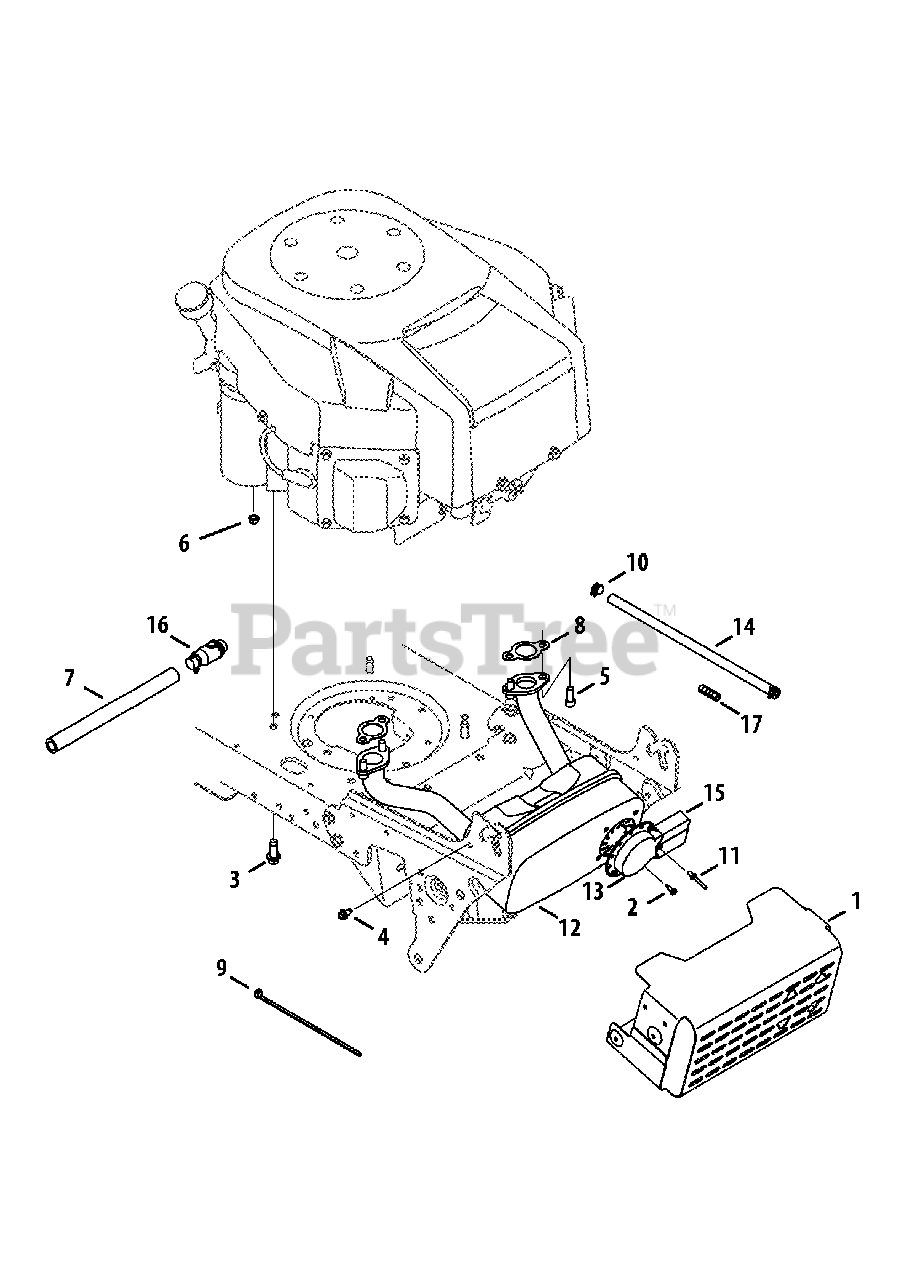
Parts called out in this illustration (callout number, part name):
2	Screw, Ab, #8-18, 0.500,
3	Screw, Self-tapping, 3/8-16, 1.000,
4	Screw, Self-tapping, 1/4-20, 0.500,
5	Screw, Socket Head, 5/16-18, .750
6	Nut, Sems, 1/4-20
7	Hose, Extension, Oil Drain
8	Gasket, Exhaust
9	Cable, Tie, 3/16 x .05 x 7.4
10	Clamp, Hose, .490 Dia.
11	Rivet, Pop, .188 Dia x .300
12	Muffler, Intek Twin
13	Deflector, Muffler
14	Hose, Fuel, Low Permeation, 1/4
15	Deflector, Muffler, Long
